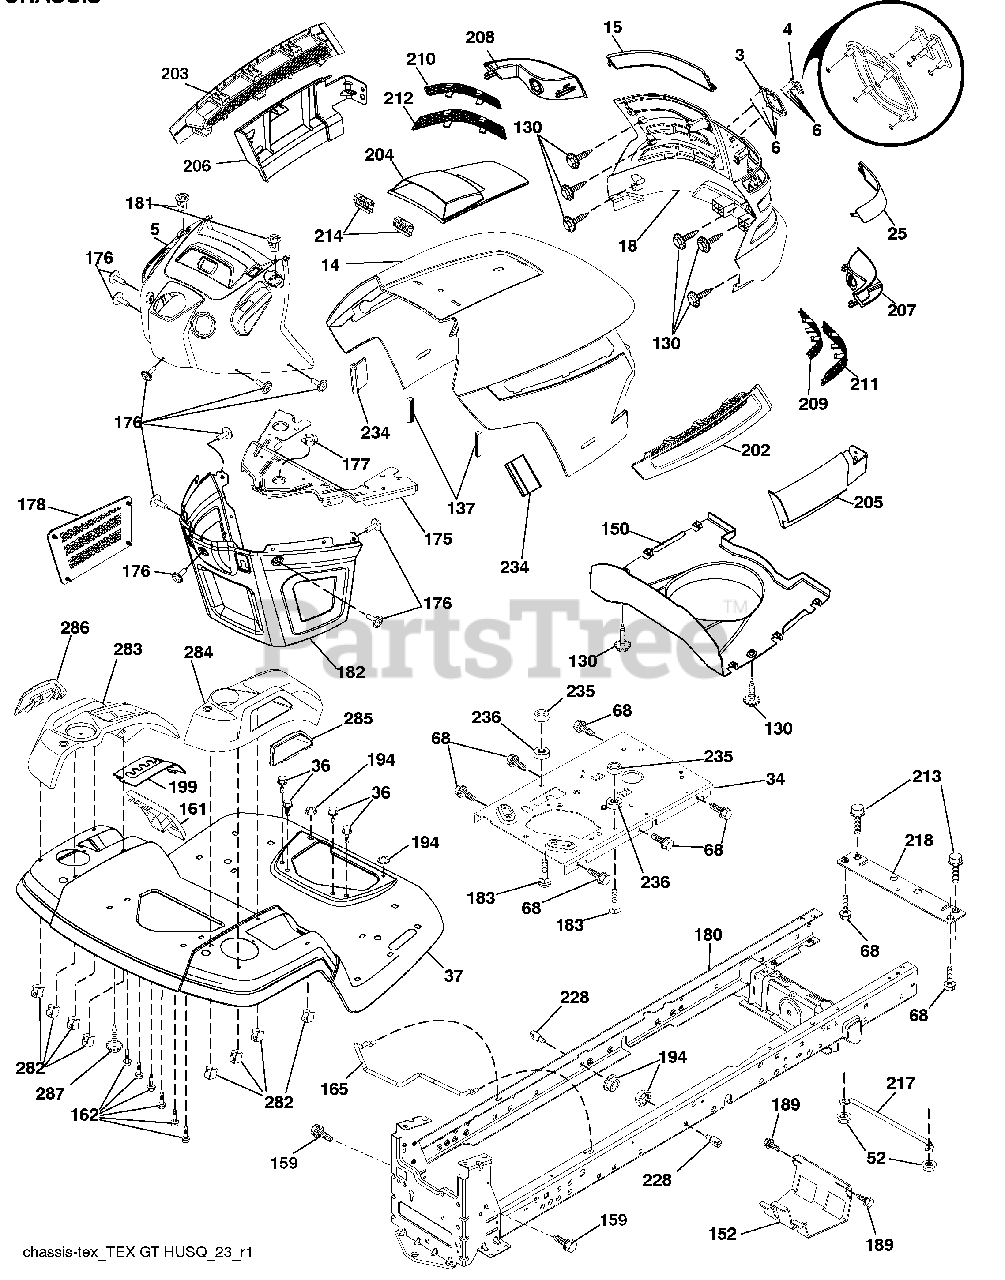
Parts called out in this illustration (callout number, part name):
3	Trim, Husq.
4	Logo
5	Dash
14	Hood
18	Grille/Lens Asm.
34	Plate Engine
36	Screw 5/16-18 X 3/4
52	Nut Lock 5/16-18
68	Screw Thdrol 5/16-18 X 1/2
130	Screw 10 X .750 Bos Thread
137	Bumper Dash
152	Shield Browning
159	Screw Hexwsh Thdr 3/8-16 X 3/4
161	Window, Fuel
162	Screw Hex Wsh 1/4 X 1/2 Unc
165	Support Tank Rear
175	Crossmember
176	Screw 10-24 X 5/8
177	Bushing Steering
178	Cargo Net Asm.
180	Chassis
181	Bushing Mtg. Fender Crgo
182	Dash Lower
183	Bolt 5/16-18 X 1-1/4 Full Thd.
189	Screw 5/16-18 X 3/4
194	Nut Lock Hex Flange 5/16-18
199	Plate Deck Lift
202	Vent Side Hood Rh
203	Vent Side Hood Lh
204	Vent Top Hood
205	Skirt Hood Side Rh
206	Skirt Hood Side Lh
209	Insert Hex Top Rh
210	Insert Hex Top Lh
211	Insert Hex Bottom Rh
212	Insert Hex Bottom Lh
213	Bolt 5/16-18 X 3/4
214	Clip Retainer Tinner
218	X-Piece Hood Stop
228	Stud Fastner
234	Bumper Hood
235	Spacer Fender
236	Nut Lock 5/16-18 Unc
282	Clip Retainer
283	Console Deck Lift
284	Console Control
285	Console Insert Rh
286	Console Insert Lh
287	Screw Hex Washead 1/4-20 X 3/8
